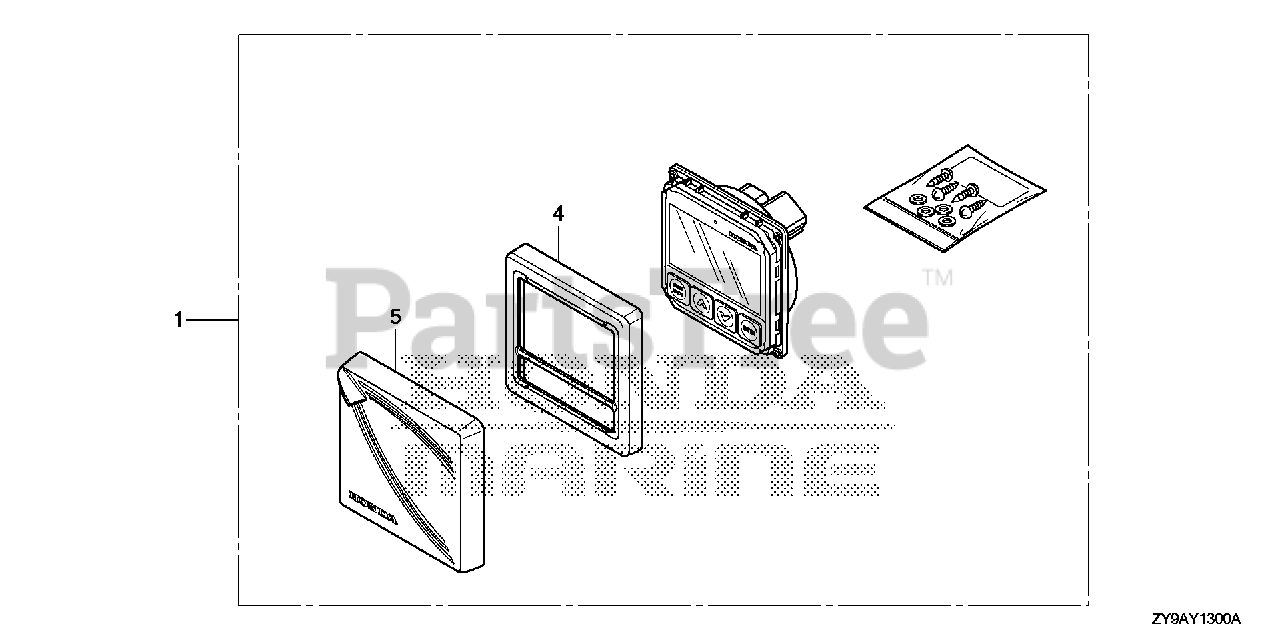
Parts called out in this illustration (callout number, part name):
1	DISPLAY KIT
2	DISPLAY ASSY.
3	DISPLAY UNIT
4	BEZEL, DISPLAY
5	COVER, DISPLAY
6	SCREW SET
